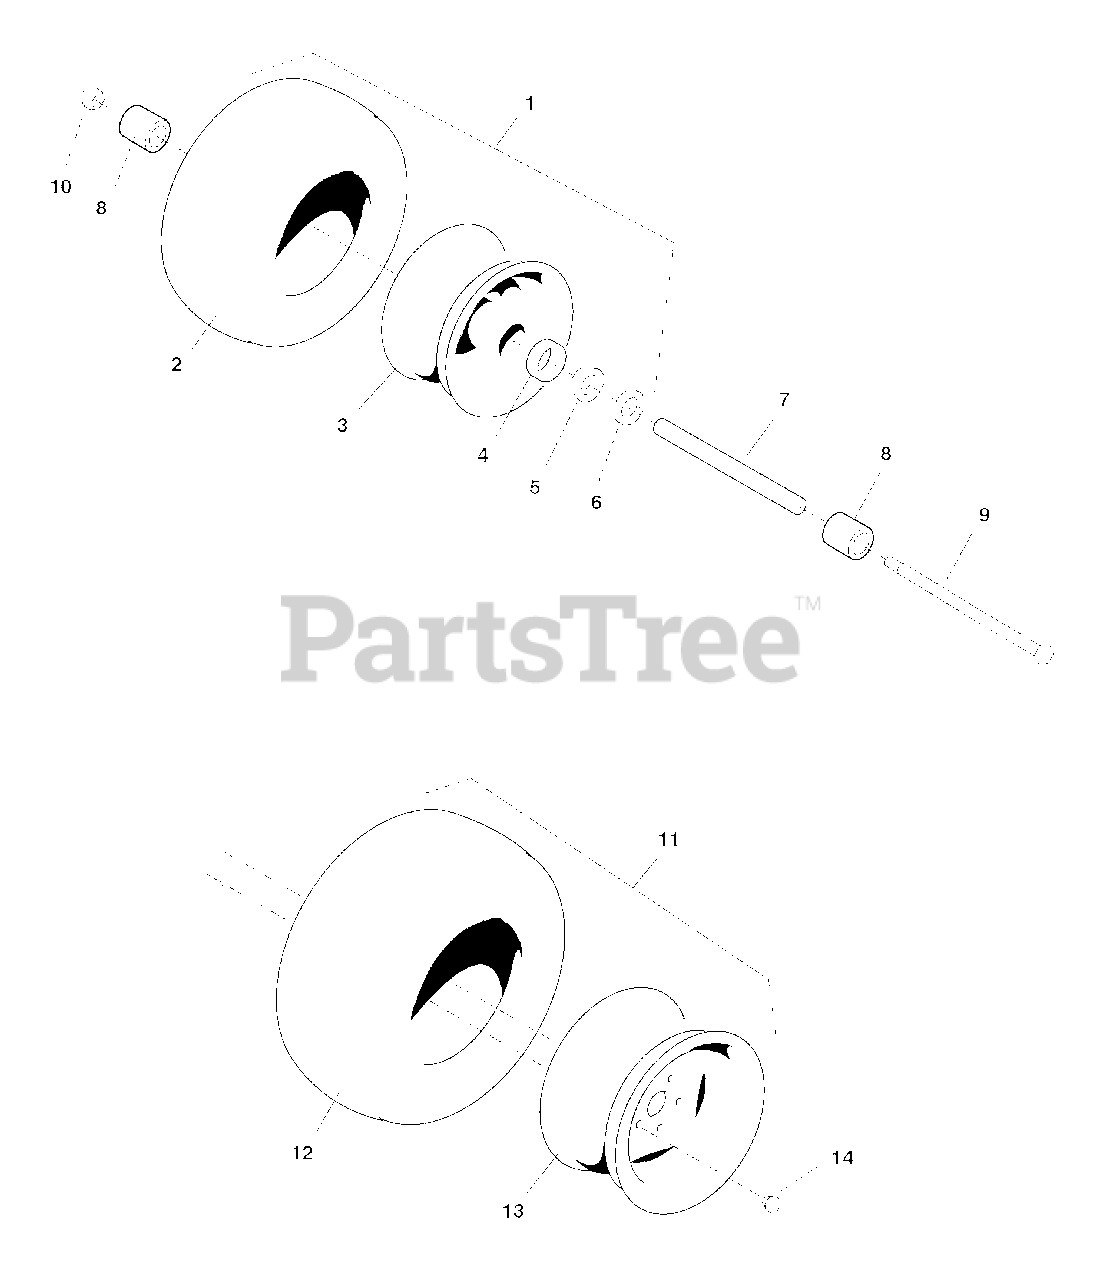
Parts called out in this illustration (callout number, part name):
1	WHEEL & TIRE ASSEMBLY, 18 x 7.5 x 8, Complete (includes Ref 2 - 6)
2	TIRE, Rear, 18 x 7.5 x 8
3	WHEEL ASSEMBLY, 8 x 3.75, Complete (includes Ref 4 - 6)
4	BEARING CUP
6	GREASE SEAL
7	STEERING TIRE AXLE
8	SPACER, 1.01 X 1.25 X 2.06
9	CAPSCREW, Hex Hd, 5/8-11 x 9-1/2
10	NUT, Hex, Side Lock, /8-11
11	WHEEL & TIRE ASSEMBLY, 20 x 10 x 8, Complete (Includes Ref 12 & 13)
12	TIRE, 20 x 10 x 8
13	WHEEL ASSEMBLY, 8 x 7
